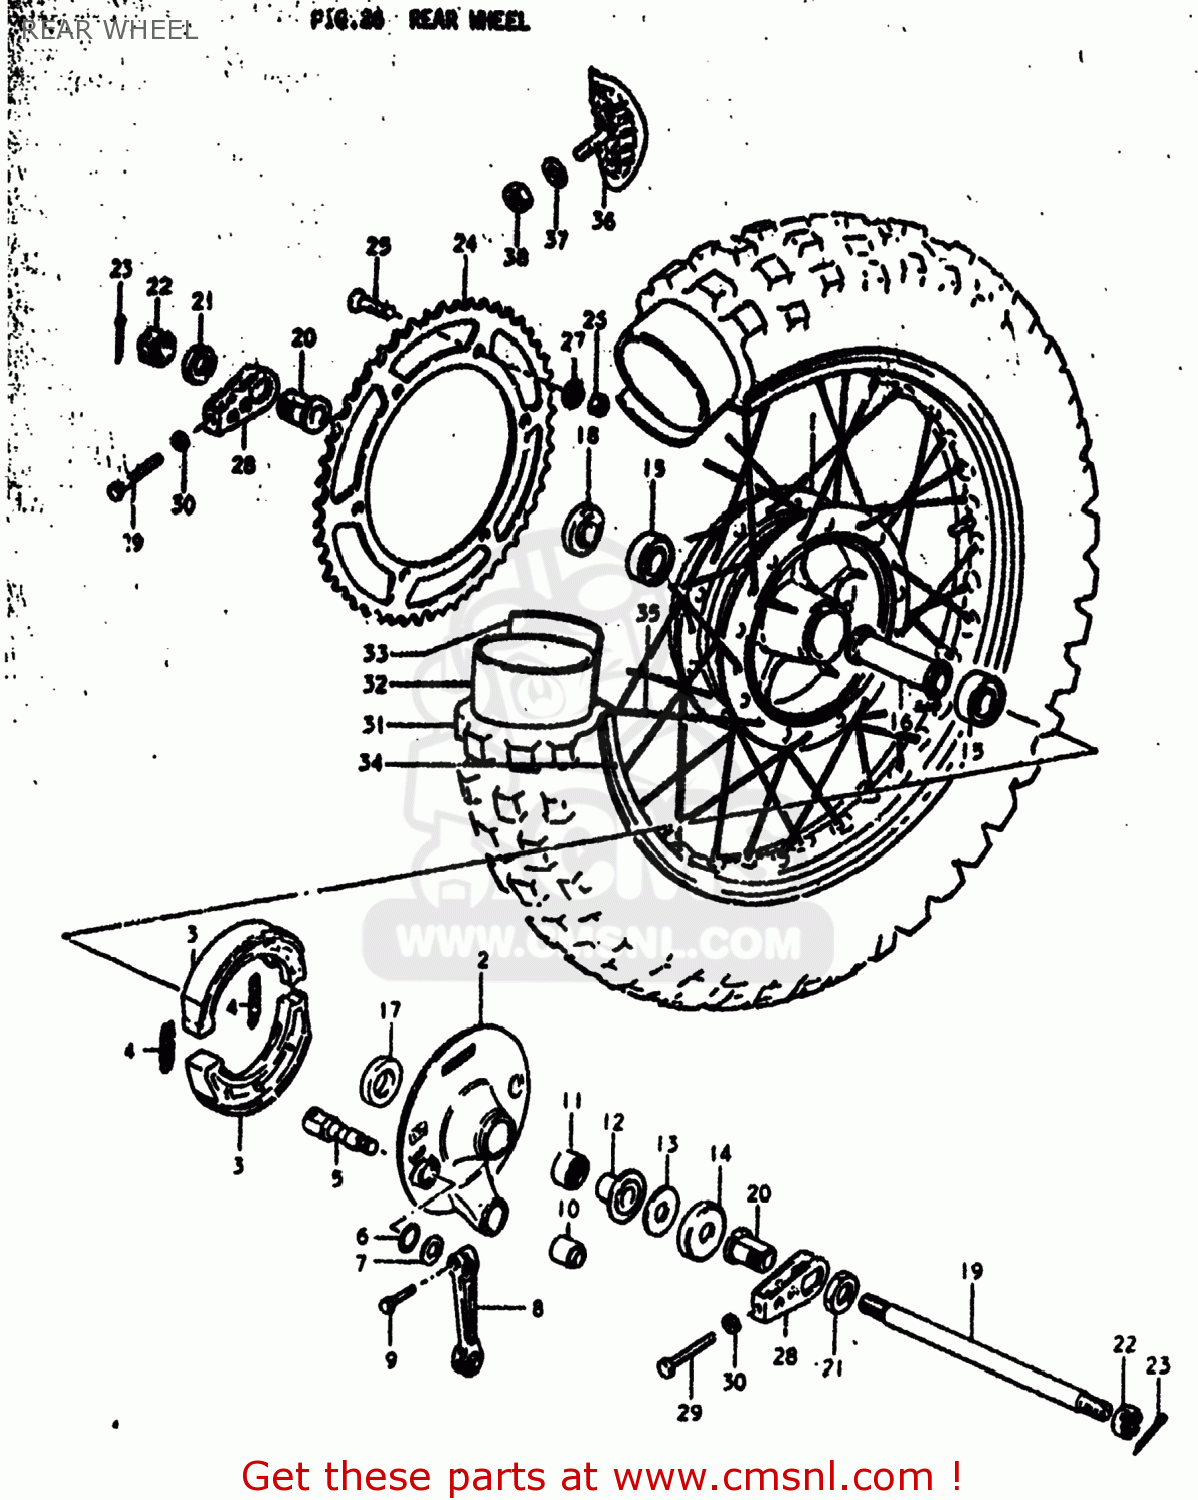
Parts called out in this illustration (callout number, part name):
1	HUB,REAR
2	PANEL,REAR HUB
3	SHOE,BRAKE
4	SPRING
5	CAM,FR BRAKE
6	O RING(D:2.5,ID:11.4)
7	WASHER(12.5X20X1)
8	LEVER,REAR BRAKE CAM
9	BOLT
10	BUSH
11	BEARING(22X29X25)
12	SPACER,REAR HUB PANEL
13	WASHER
14	COVER, PANEL DUST SEAL
15	BEARING
16	SPACER,REAR HUB BEARING
17	SPACER,REAR AXLE,RIGHT
18	SPACER,REAR AXLE,RIGHT
19	AXLE,REAR
20	SPACER,CHAIN ADJUSTER
21	NUT
22	NUT
23	PIN 30X40
24	SPROCKET,REAR
25	SCREW
26	NUT
27	WASHER
28	ADJUSTER,CHAIN
29	BOLT
30	NUT
31	TIRE
32	TUBE,INNER
33	PROTECTOR,WHEEL,INNER
34	RIM,REAR WHEEL
35	SPOKE SET,REAR
36	STOPPER,BEAD
37	WASHER
38	NUT
